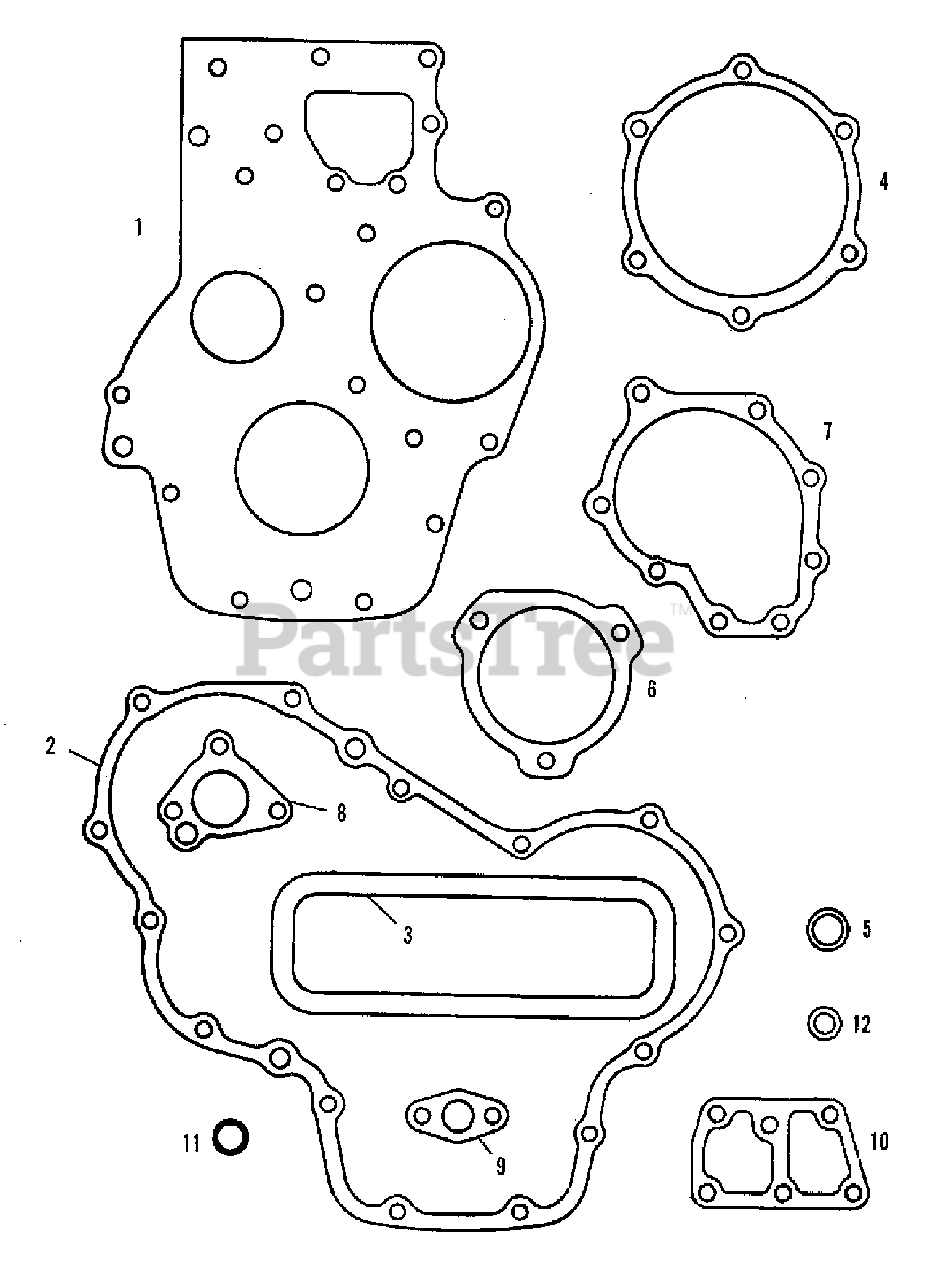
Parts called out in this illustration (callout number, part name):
1	GASKET, front plate
2	GASKET, gear cover
3	GASKET, chamber cover
4	GASKET, rear oil seal
5	GASKET, oil drain
6	GASKET, injection Pump
7	GASKET, water pump
8	GASKET, oil pump
9	GASKET, oil suction tube
10	GASKET, oil control housing
11	O-RING, oil control housing
12	GASKET, lube oil tube
